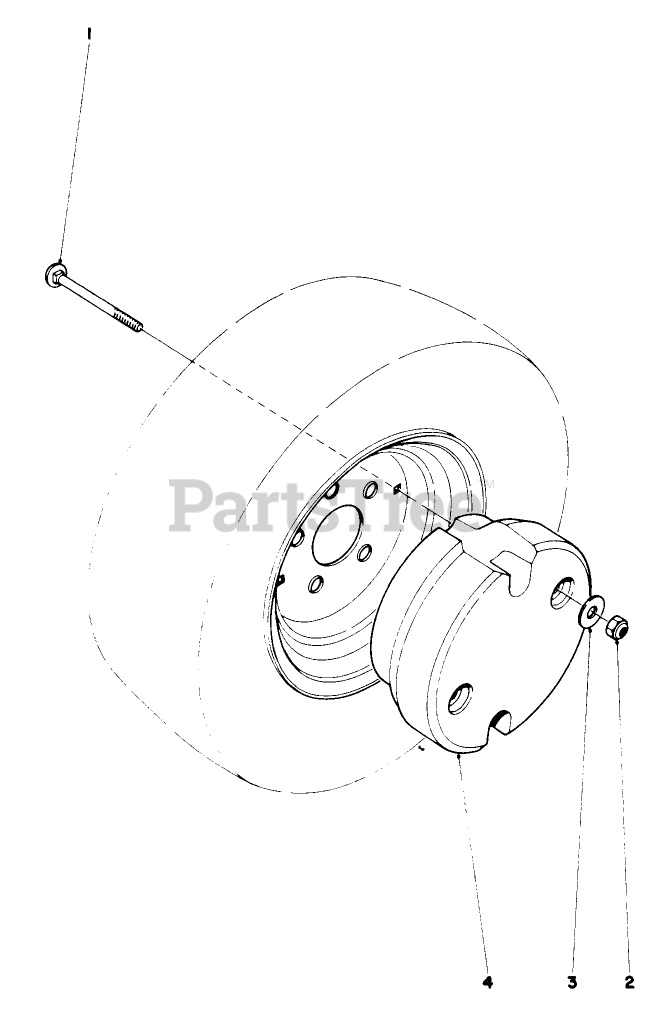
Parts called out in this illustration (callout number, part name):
1	SCREW-CARR
2	NUT-LOCK, NI
3	WASHER-FLAT
4	Wheel Weight
